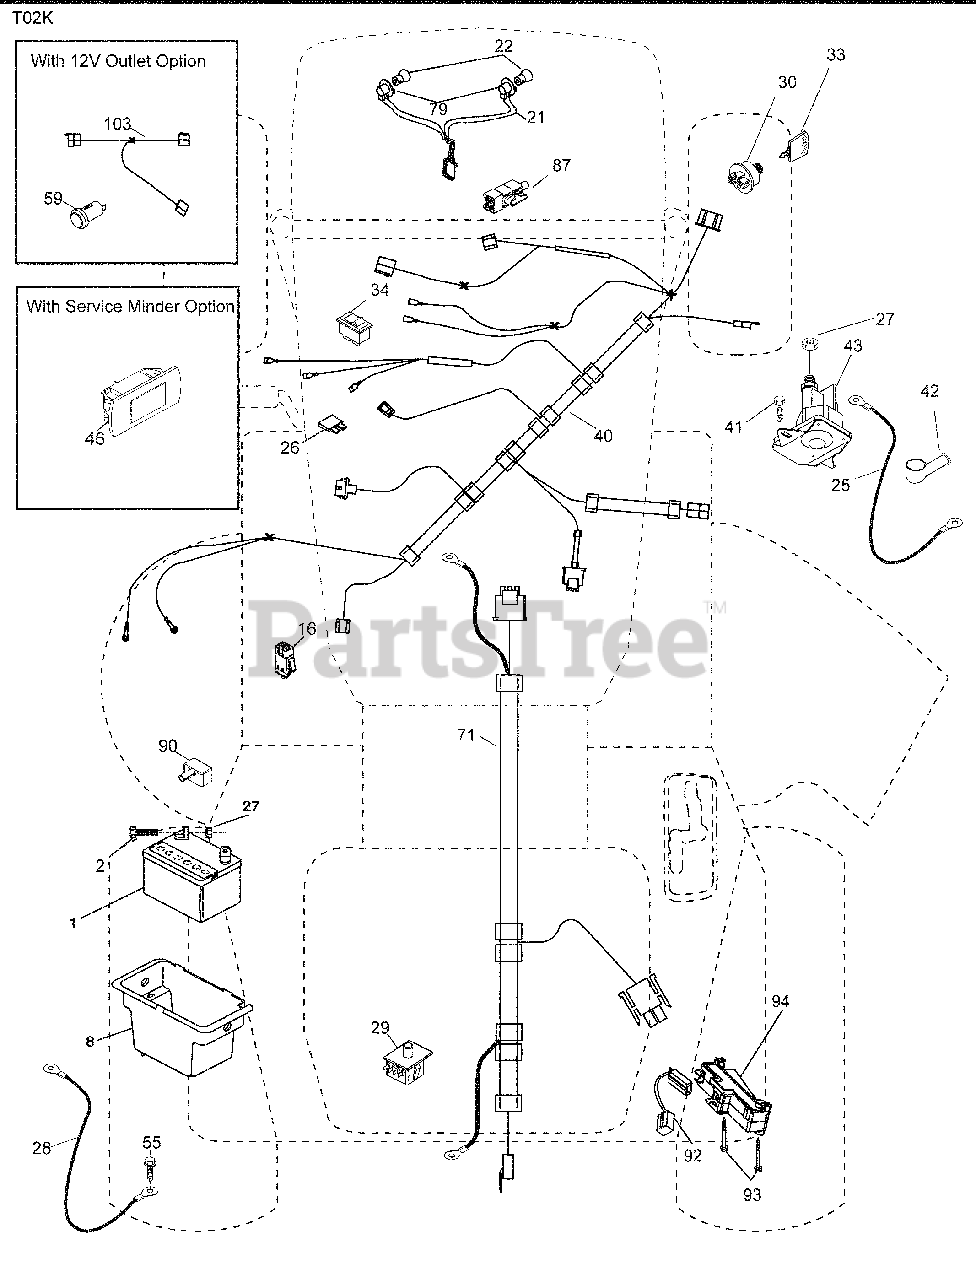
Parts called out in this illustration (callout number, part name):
1	Battery
2	Bolt Hex Head 1/4-20 x 3/4
8	Box Battery
16	Switch Interlock Push-In
21	Harness Socket Light w/4152J
22	Bulb Light
25	Cable Starter
27	Nut Keps Hex 1/4-20 unc
28	Cable, Ground
29	Switch, Seat
30	Switch, Ign
33	Key, Ignition
34	Switch Light/Reset
40	Harness Ign.
41	Screw Thd Cut 1/4-20 x 1/2
42	Cover, Terminal
43	Solenoid
55	Screw Thdrol 5/16-18 x 3/4 TYTT
71	Harness Ign. Dash
79	Socket Asm. Bulb
87	Switch Interlock Clutch Cable
90	Cover Terminal
92	Harness Pigtail Reverse Switch
93	Screw Plastite 10-14 x 2.0
94	Module Reverse ROS
